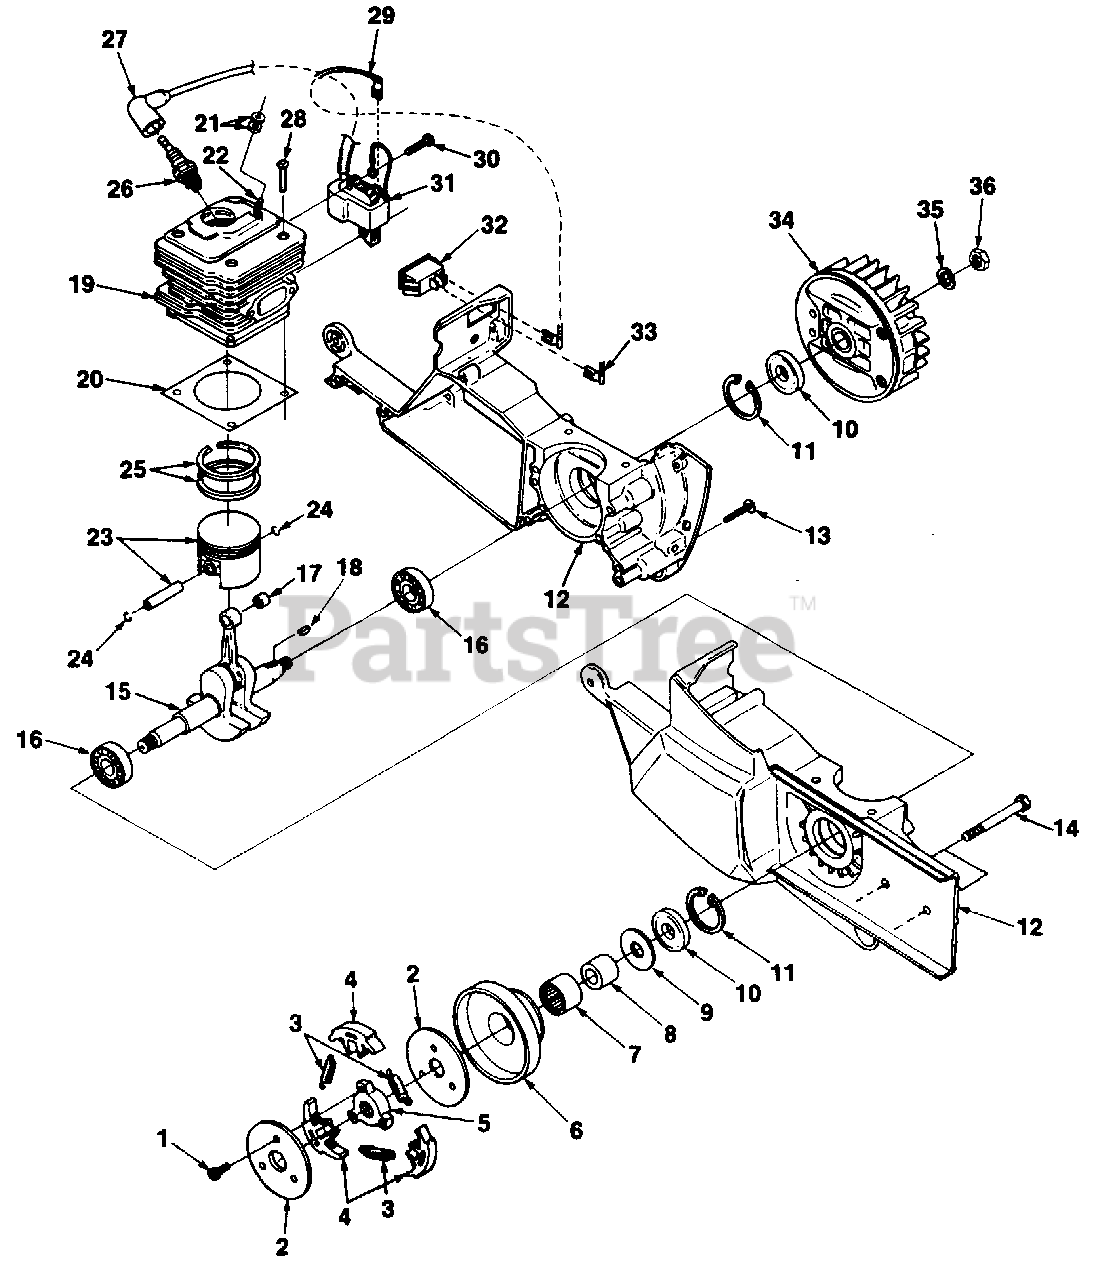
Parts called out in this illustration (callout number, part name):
1	SCREW- Mach. Hex hd. (8-32 x 3/8")
2	COVER- Clutch
3	SPRING- Clutch
4	SHOE- Clutch
5	CLUTCH- Spider
6	PULLEY- Drum & Bearing
7	BEARING- Needle
8	RACE- Inner
9	WASHER- Thrust
10	SEAL- Main
11	RETAINER- Bearing
12	CRANKCASE
13	SCREW- Truss hd. (10-24 x 1 1/4")
14	BOLT- Wheel Arm
15	CRANKSHAFT
16	BEARING- Ball
17	BEARING- Roll
18	KEY- Woodruff
19	CYLINDER & PISTON ASSY.
20	GASKET- Cylinder
22	STUD- (10-24 x 1.06")
24	RING- Retaining
25	RING- Piston
26	SPARK PLUG (CJ6Y)
27	SPARK PLUG BOOT KIT
28	SCREW- Pan hd. (12-24 x 3/4")
29	IGNITION GROUND WIRE
30	SCREW- Pan hd. (8-32 x 5/8")
31	IGNITION MODULE (Sems/Walbro)
32	SWITCH
33	GROUND WIRE
34	ROTOR
35	WASHER- Lock
36	NUT- Jam
